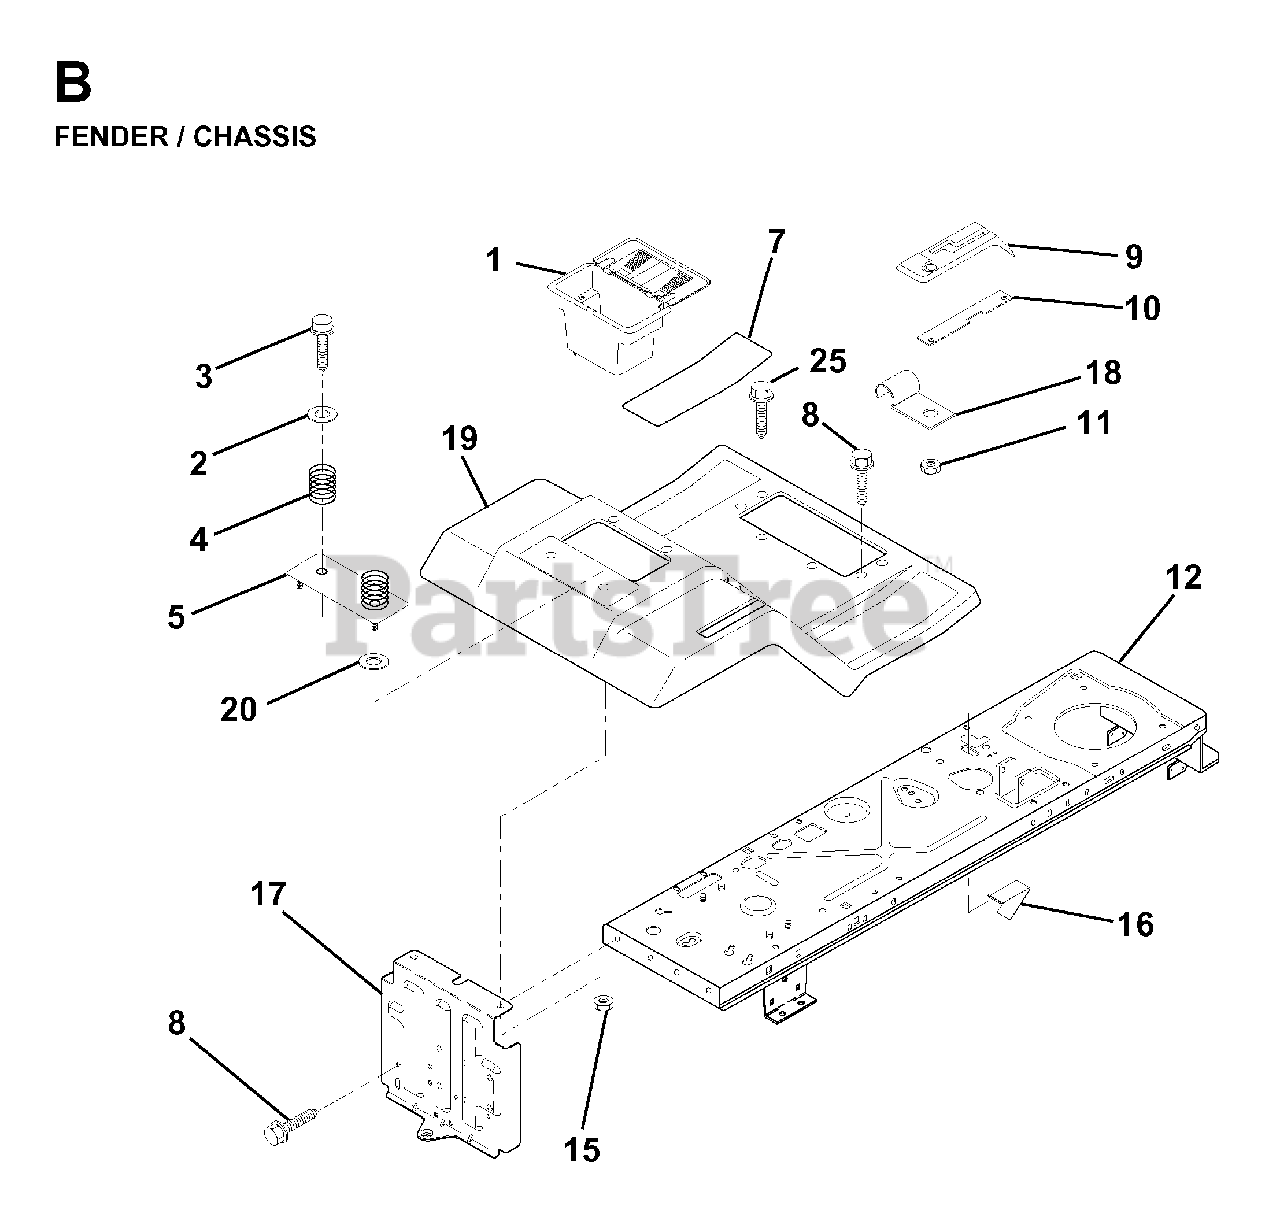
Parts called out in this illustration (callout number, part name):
1	CASE BATTERY MECH HINGE
3	SCREW
4	SPRING COMPRESSION
7	PAD FOOTREST
8	SCREW
10	BAR, SHIFT LOCK
18	CLIP,INSULATOR
20	WASHER
